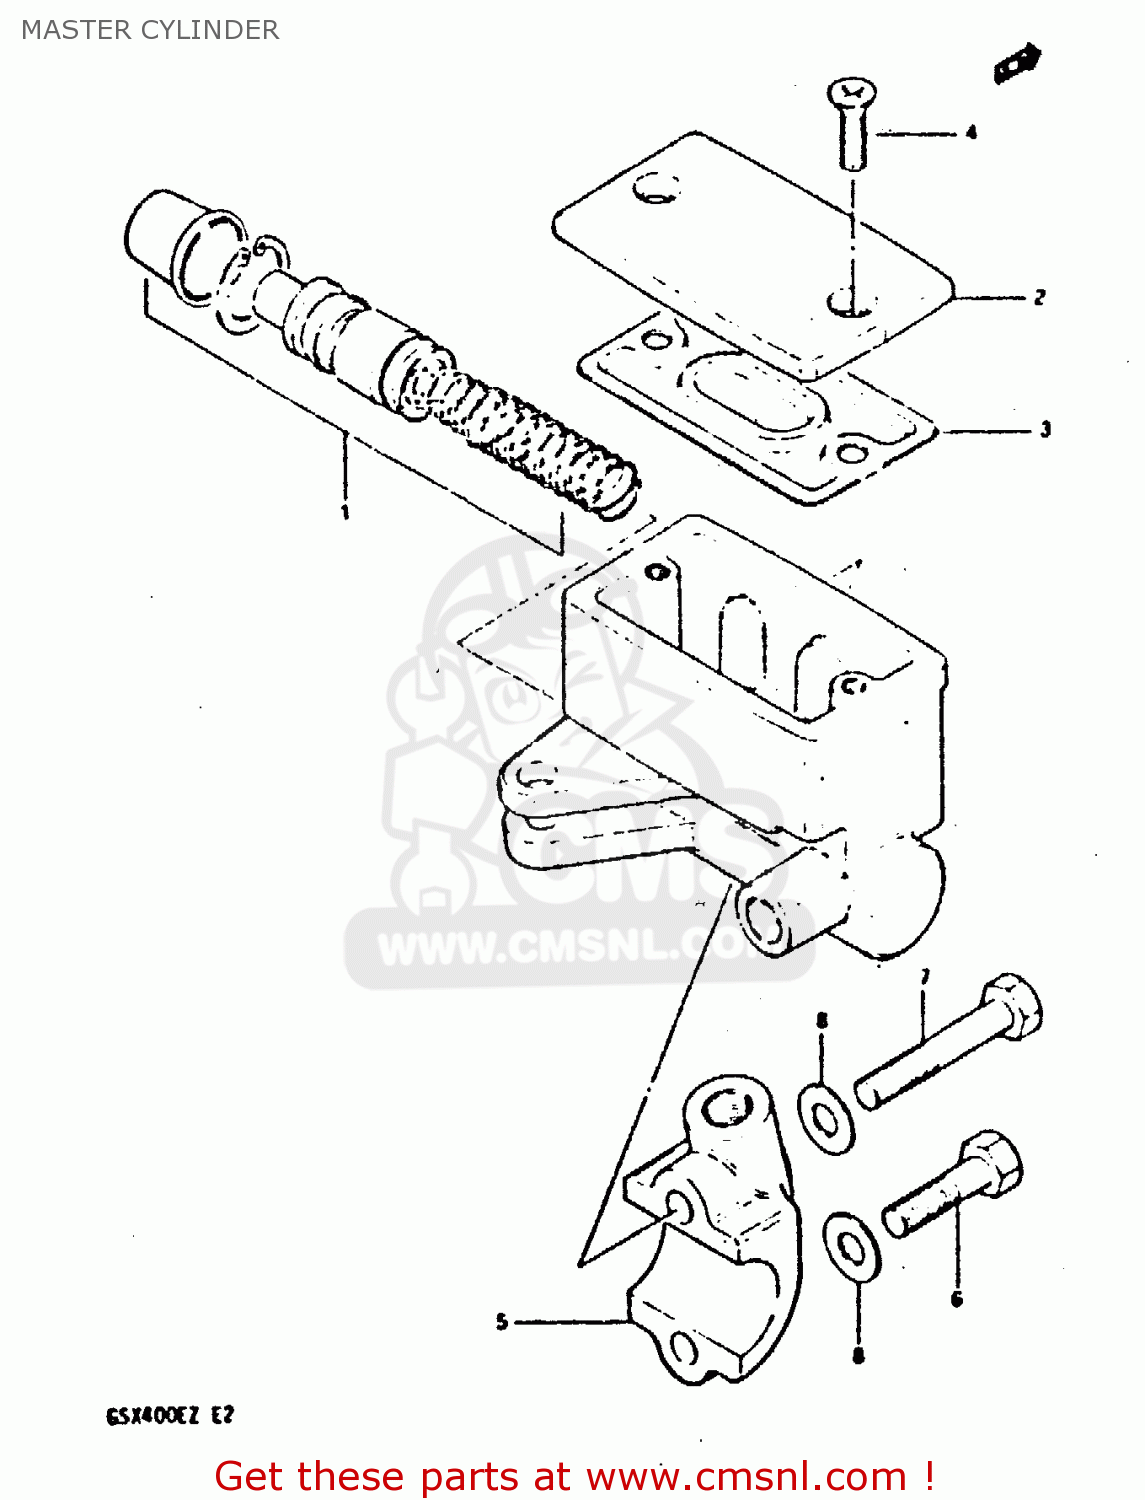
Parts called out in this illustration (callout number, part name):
1	PISTON & CUP SET
2	CAP
3	4
4	SCREW
5	HOLDER
6	BOLT
7	BOLT 6X40
8	LOCK WASHER
